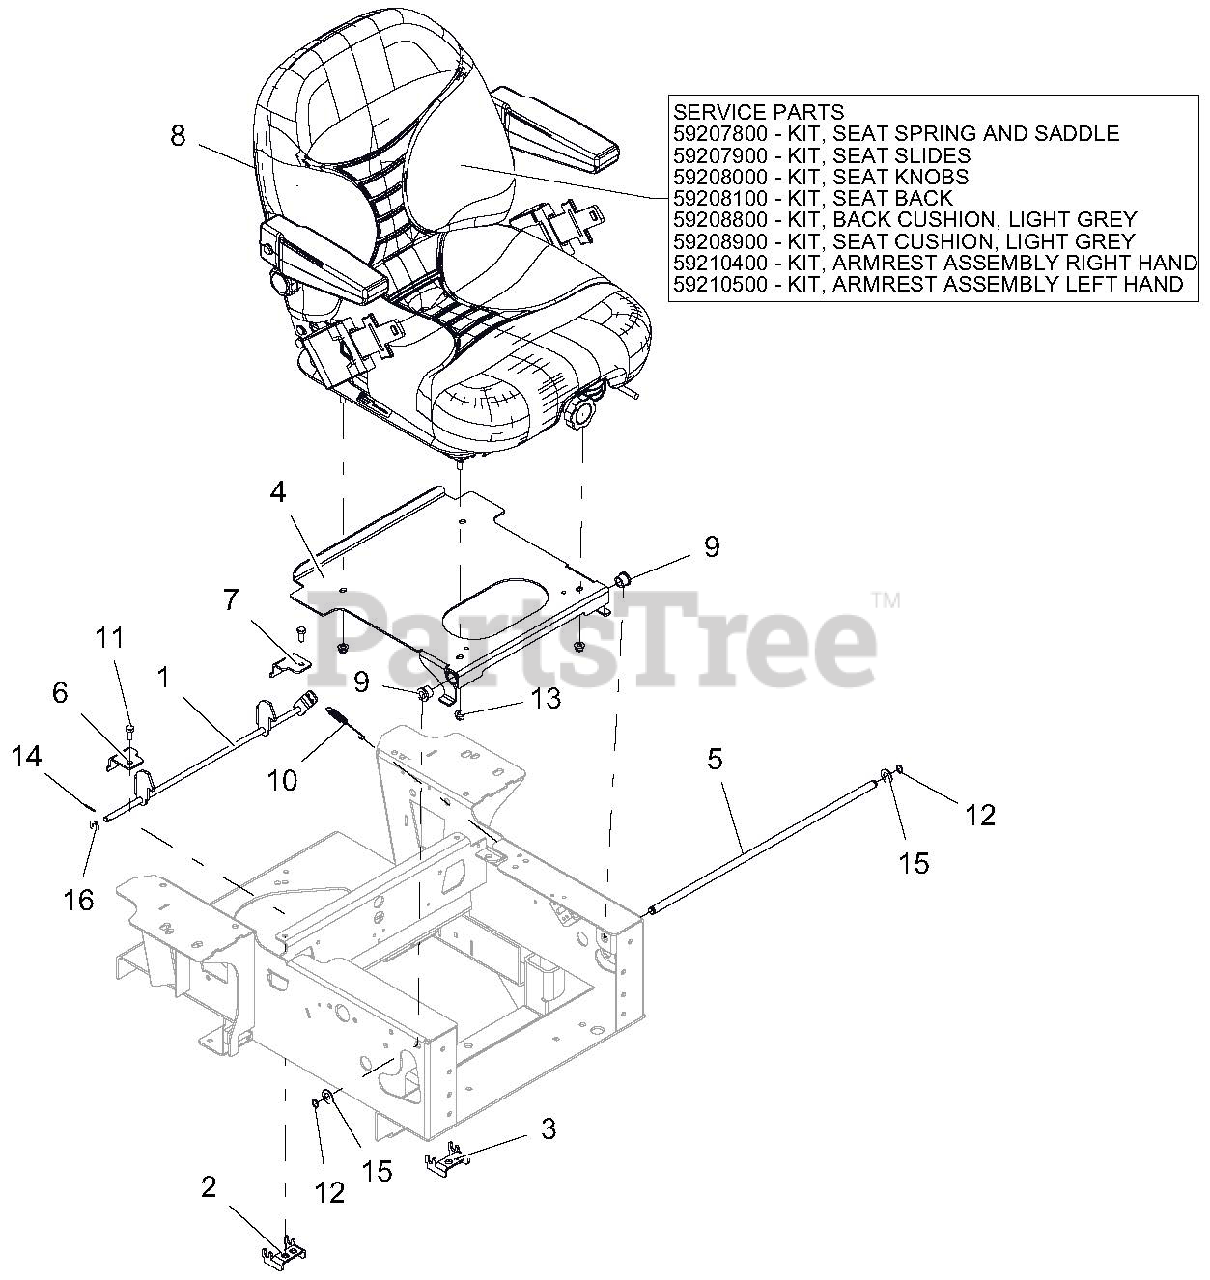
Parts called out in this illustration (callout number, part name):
1	WLDMT, PRO-TURN SEAT LATCH-BLACK
2	WLDMT, PT/PT100 RH SEAT LATCH MOUNT-BLACK
3	WLDMT, PT/PT100 LH SEAT LATCH MOUNT-BLACK
4	WLDMT, PRO-TURN 100 SEAT PLATE - BLK
5	SHAFT, PT/PT100 SEAT PIVOT
6	MOUNT, PT/PT100 RH TOP SEAT LATCH-BLACK
7	MOUNT, PT/PT100 LH TOP SEAT LATCH-BLACK
8	SEAT, SUSPENSION W/SEAT BELT, LT GRAY
8	KIT, SEAT SPRING AND SADDLE
8	KIT, SEAT SLIDES
8	KIT, SEAT KNOBS
8	KIT, SEAT BACK
8	KIT, BACK CUSHION, LIGHT GREY
8	KIT, SEAT CUSHION, LIGHT GREY
8	KIT, ARMREST ASSEMBLY RIGHT HAND
8	KIT, ARMREST ASSEMBLY LEFT HAND
9	BSHG, SHLDR EP .358-16X.30 HEX YZ
10	SPRG, EXTENSION
11	BLT-HEX .31-18X.75 GR5 YWZC
12	RG-RTNG-EXT .500x.050
13	NUT-LK-NYL-FLG .31-18 YWZC
14	@PIN-CTR .09X.75 EXTPRSQCT YWZ
15	WSHR-FL-STL .531X1.000X.063 YWZC
16	WSHR-FL-STL.406X.812X.065 YWZ
